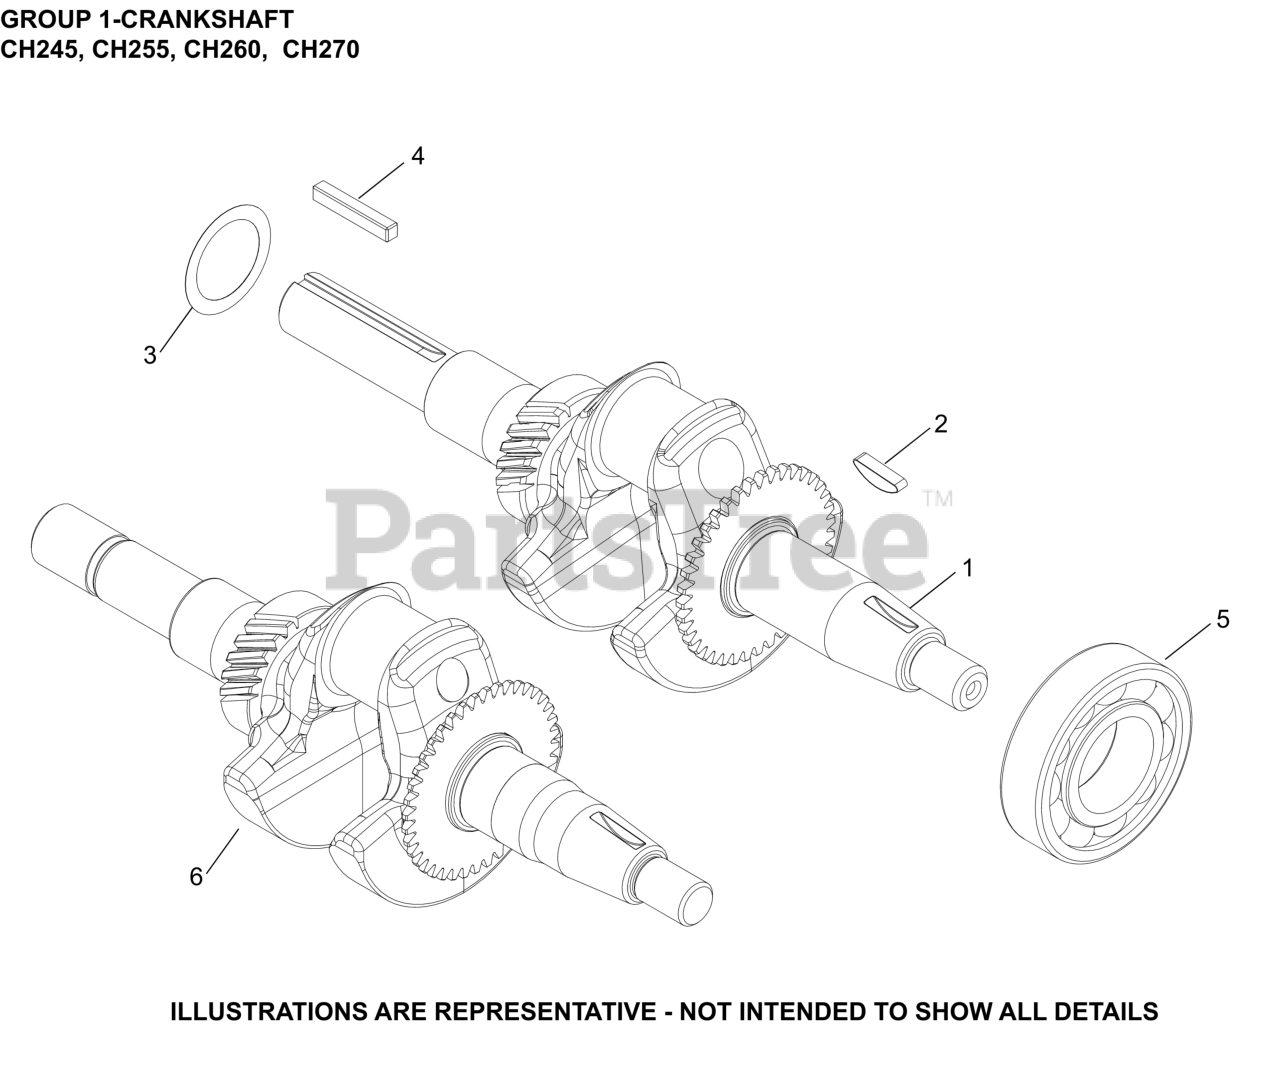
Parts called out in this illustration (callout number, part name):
1	CRANKSHAFT, ASSEMBLY
2	KEY, FLYWHEEL
3	KIT, THRUST SHIM
4	KEY, SQUARE
